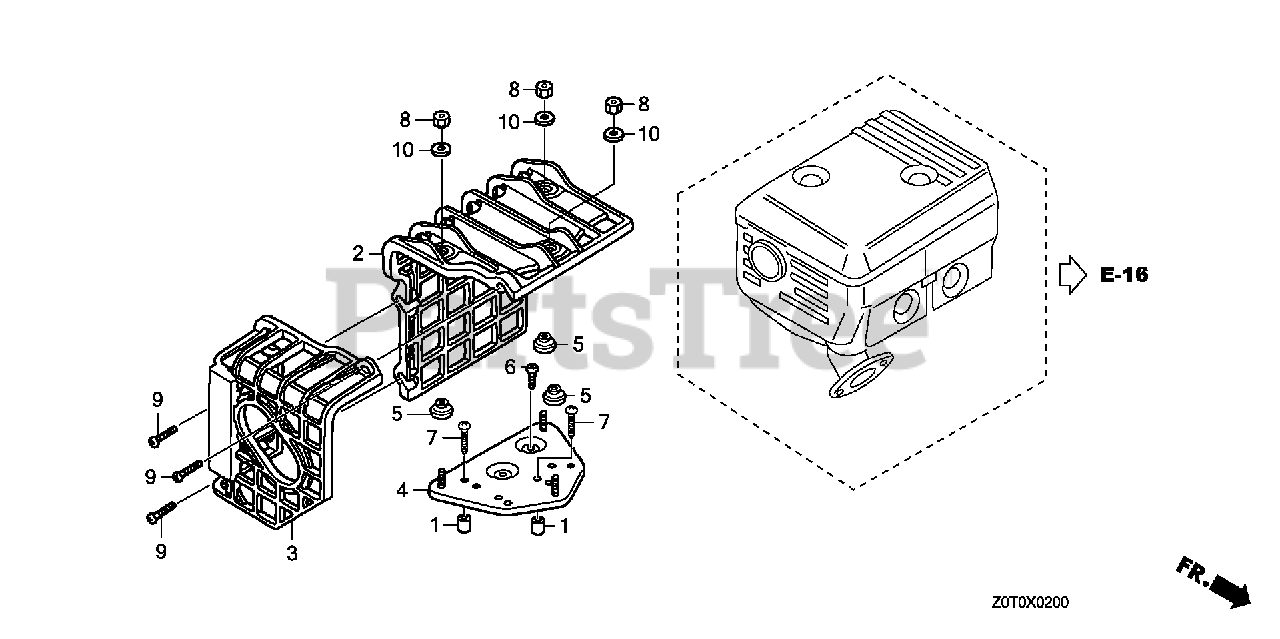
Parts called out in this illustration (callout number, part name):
1	COLLAR, AIR CLEANER HOUSING
2	COVER, MUFFLER
3	COVER, RR. MUFFLER
4	BASE, MUFFLER COVER
5	SPACER, MUFFLER COVER
6	SCREW, TAPPING (5X8)
7	SCREW, TAPPING (5X25)
8	NUT, HEX. (5MM)
9	SCREW-WASHER (6X20)
10	WASHER, PLAIN (5MM)
